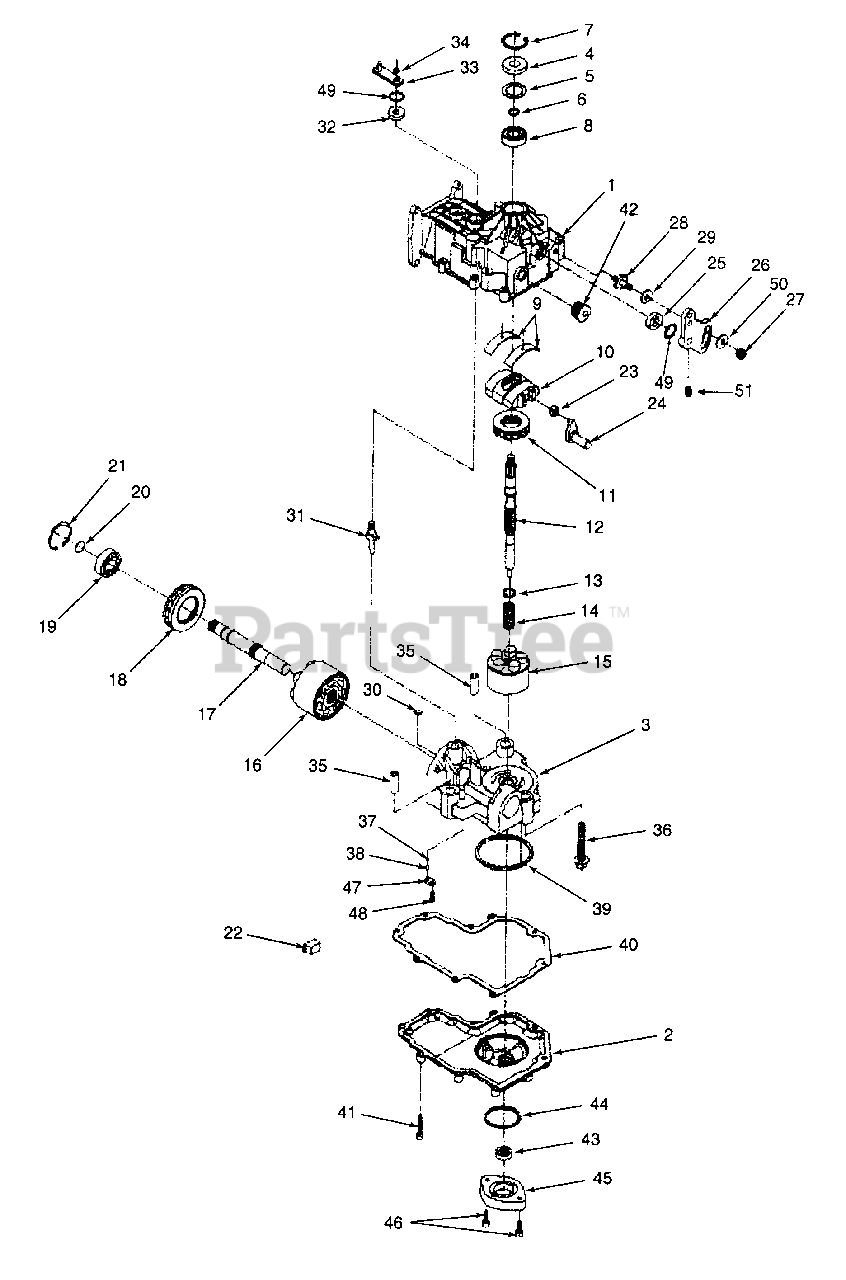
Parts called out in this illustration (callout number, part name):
1	Housing Ass'y Upper
2	Lower Housing
3	Center Section Assembly
6	Wire Retaining Ring
7	Retaining Ring
8	Ball Bearing
9	Cradle Bearing
10	Variable Swashplate
11	Thrust Bearing
13	Block Thrust Washer
15	Cylinder Block Assembly
16	Cylinder Block Assembly
17	Output Shaft (Motor)
18	Thrust Bearing
19	Ball Bearing
20	Wire Retaining Ring
21	Retaining Ring
22	Motor Bearing Retaining
27	Hex Lock Nut 5/16-24
28	Short Stud 5/16-24
29	Friction Puck
30	Bypass Plate
31	Bypass Actuator
34	Retaining Ring
37	Charge Relief Spring
41	Self Tapping Screw
43	Gerotor Assembly
45	Gerotor Cover
47	Relief Plate
49	Retaining Ring
